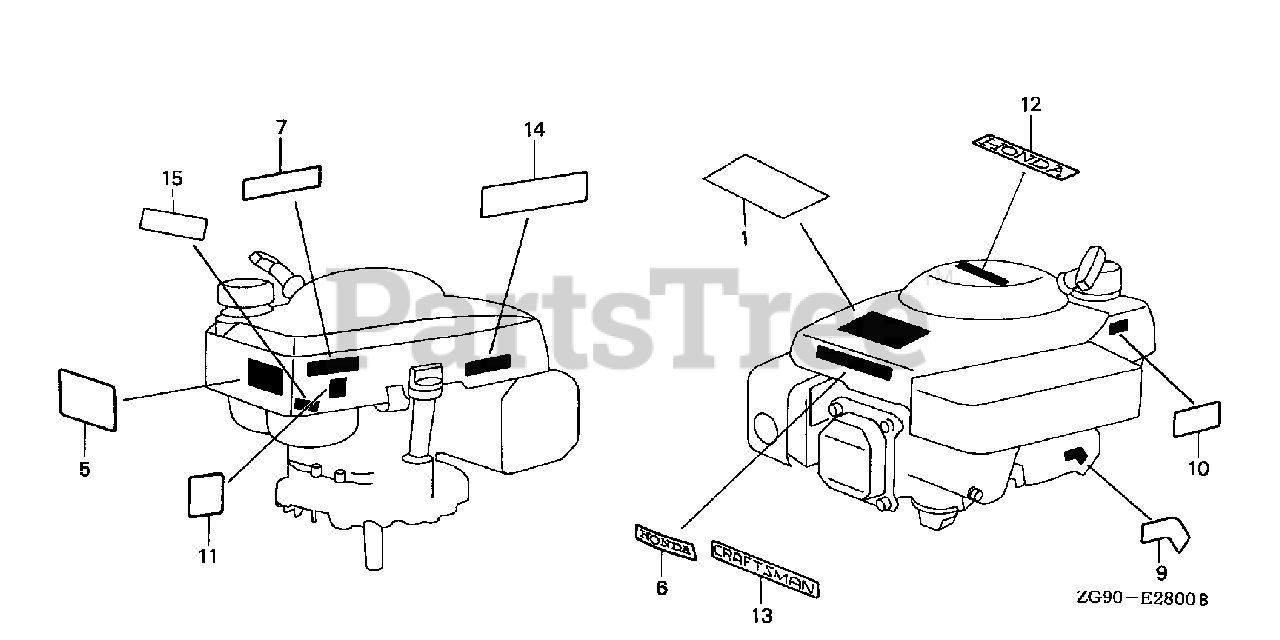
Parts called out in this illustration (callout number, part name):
1	EMBLEM (GXV140 5.0)
1	EMBLEM (5.0) (AH)
7	MARK, HONDA
10	LABEL, FUEL CAUTION
